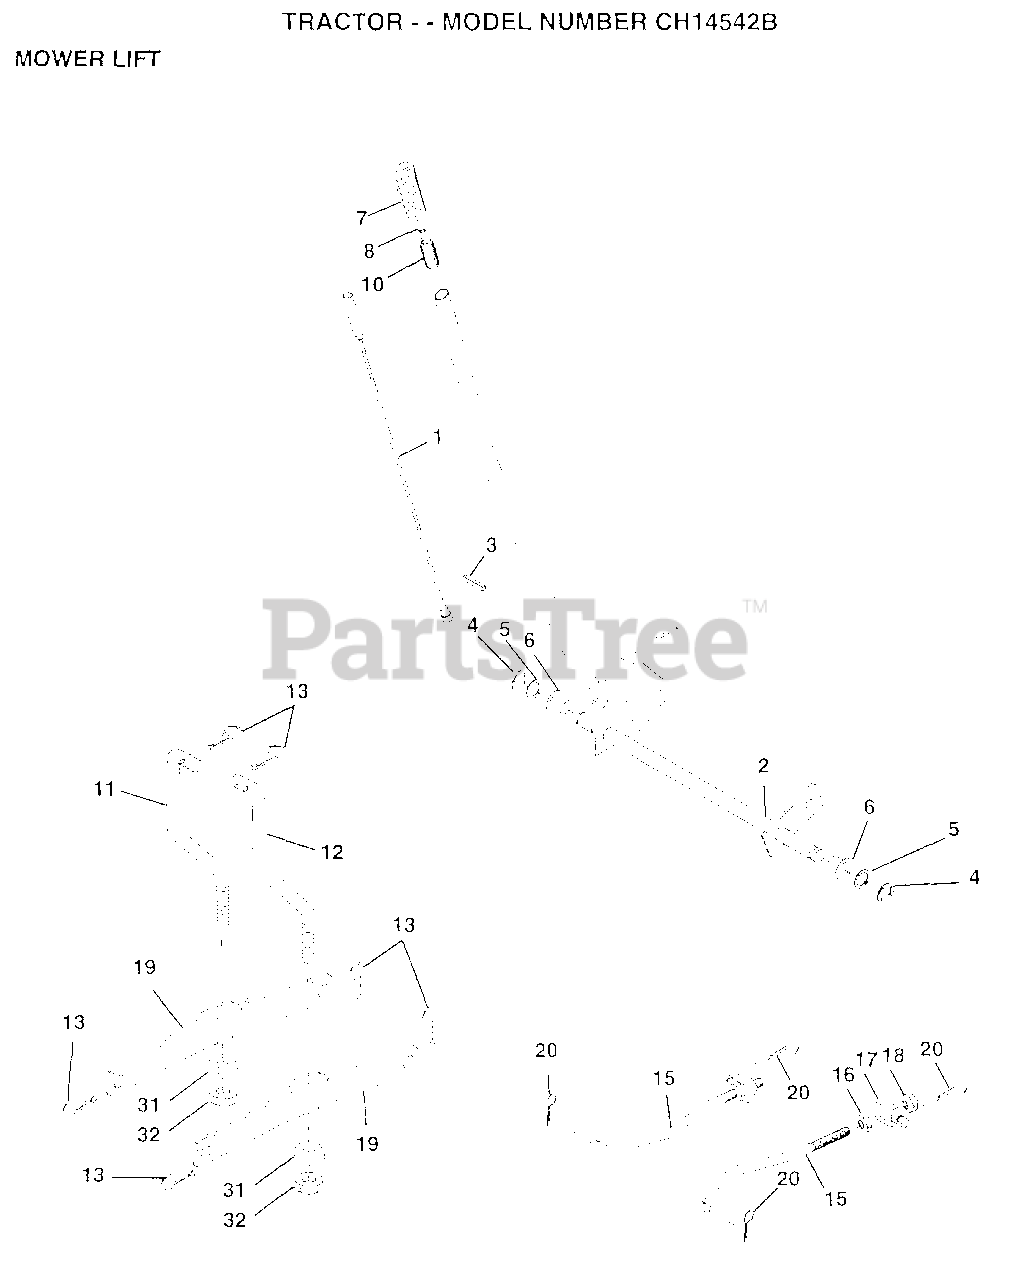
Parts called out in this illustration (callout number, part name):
1	WIRE ASM
2	HANDLE.LIFT.LH.
3	PIN GROOVE
5	WASHER
6	NYLON BEARING
7	GRIP
15	LINK.FRONT
16	NUT
17	TRUNION
18	NUT.LK.W/WSH.1/2.
19	ARM SUSP REAR
20	RETAINER.SPRING
31	BEARING PVT LH
32	NUT.CROWNLOCK.3/8
